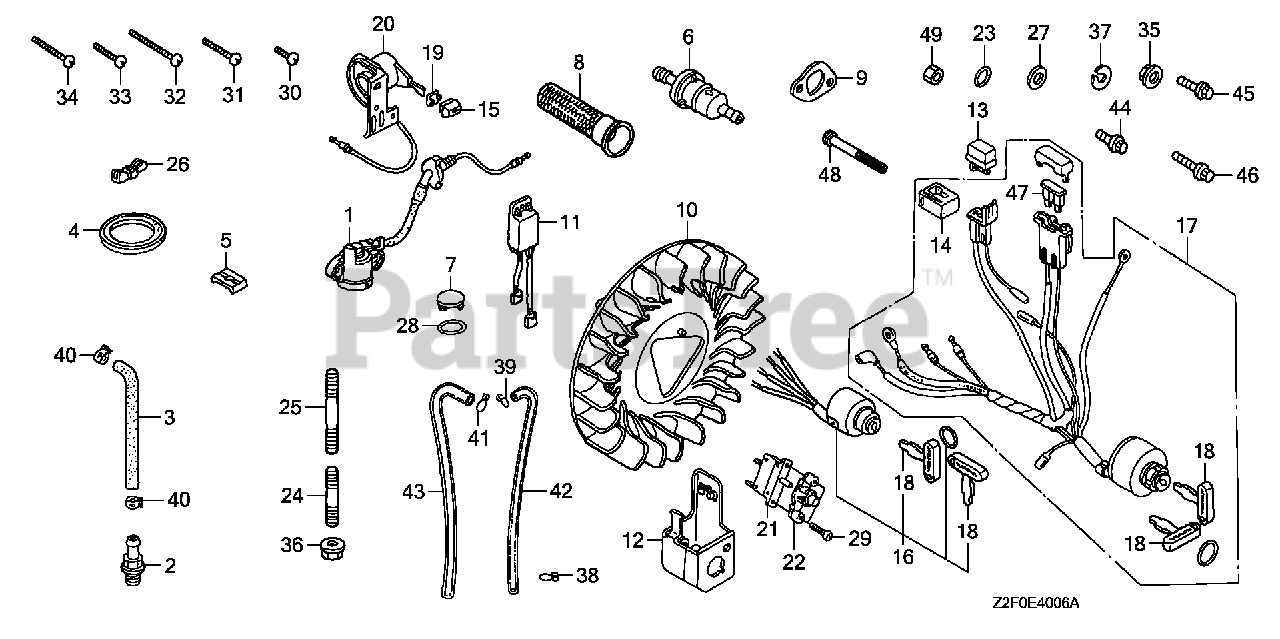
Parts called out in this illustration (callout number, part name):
24	BOLT, STUD (10X32)
25	BOLT, STUD (10X60)
36	NUT, FLANGE (10MM)
